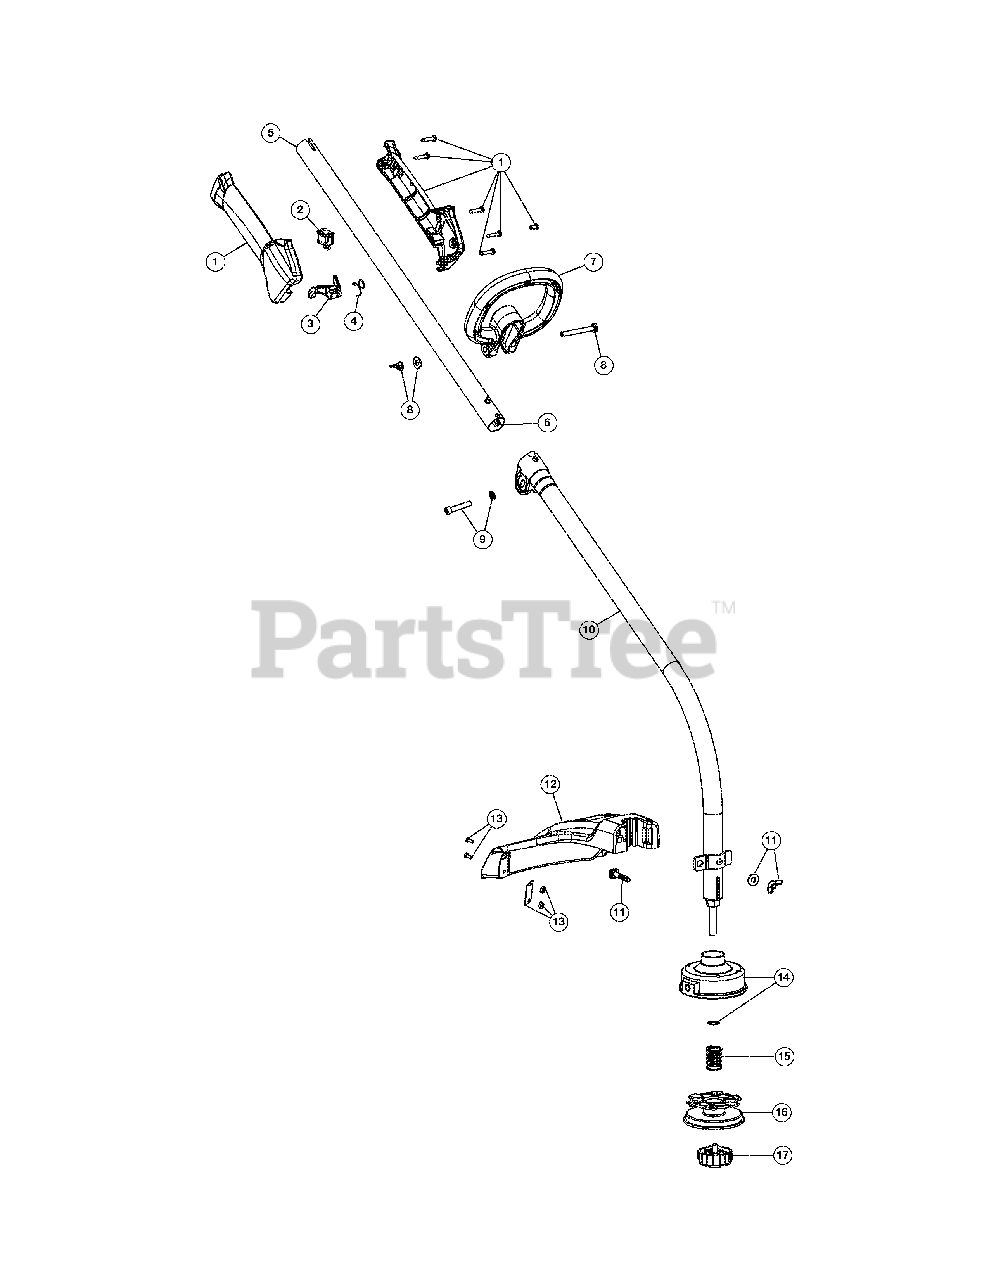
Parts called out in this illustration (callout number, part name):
1	Throttle Housing Assembly (includes 3-4)
3	Throttle Trigger
4	Throttle Trigger Spring
5	Upper Shaft Housing Assembly (includes 6)
6	Upper Flexible Drive Shaft
7	D-Handle (includes 8)
8	D-Handle Hardware Assembly
9	Clamp Hardware
10	Lower Shaft Housing Assembly (includes 9 & 14)
11	Shield Mounting Hardware
12	Shield Assembly (includes 11 & 13)
13	Blade Assembly
14	Outer Spool w/Retainer
16	Inner Reel
17	Bump Knob Assembly
